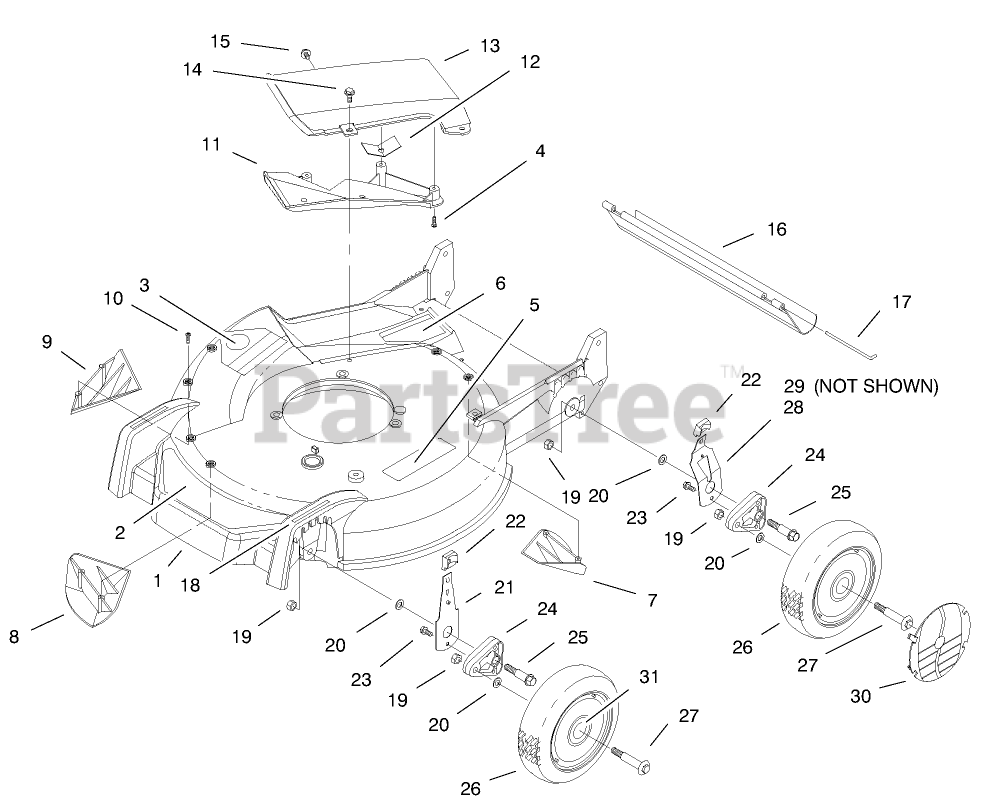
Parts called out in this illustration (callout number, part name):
1	HOUSING W/DECALS
2	DECAL - DECK
3	DECAL-DANGER
4	Screw-PPH
6	DECAL - DANGER
7	KICKER-REAR
8	KICKER-FRONT
9	KICKER-RH
10	SCREW-PPH
11	Deflector-Recycler
12	Guard-Cover
14	SCREW-HWH
15	SCREW AND WASHER ASM
17	ROD-SHIELD
19	NUT-LOCK
20	WASHER
21	FRONT SPRING ARM ASM
22	KNOB-ARM
23	SCREW-HWH
25	BOLT-SHOULDER
26	WHEEL AND TIRE ASM
28	RH SPRING ARM ASM
29	LH SPRING ARM ASM
31	BUSHING
